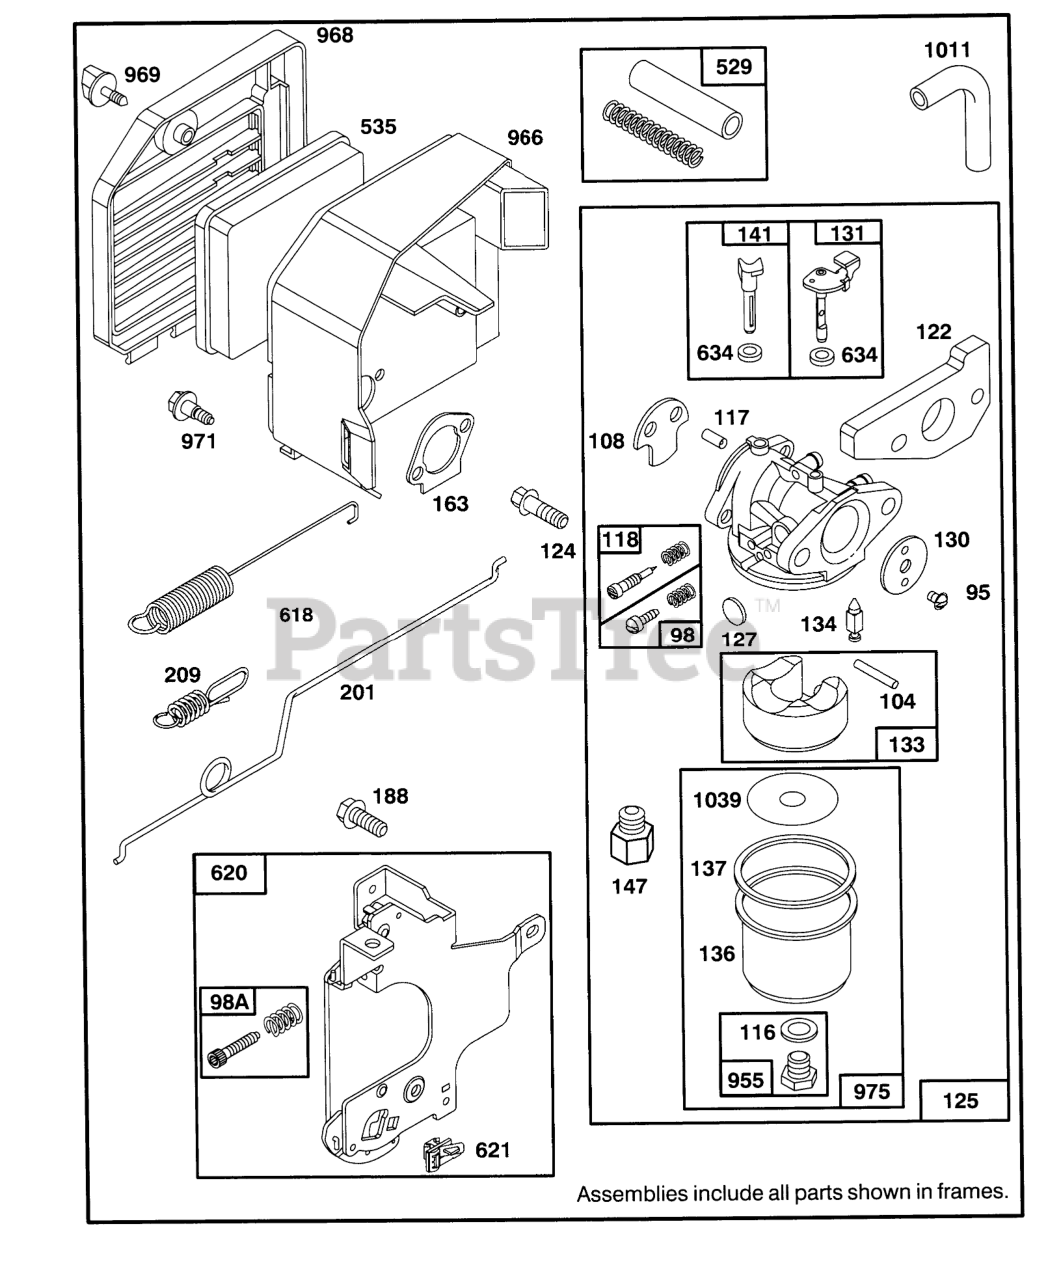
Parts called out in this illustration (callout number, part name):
95	SCREW - ROUND HEAD
98	IDLE ADJUSTING SCREW
98A	SPEED ADJUST. SCREW ASM
104	FLOAT HINGE PIN
108	CHOKE VALVE
116	SEALING GASKET
117	JET
118	VALVE KIT - NEEDLE
122	ADAPTER ASSEMBLY
124	HEX HEAD SCREW
125	CARBURETOR ASSEMBLY
130	THROTTLE VALVE
131	THROTTLE SHAFT
133	FLOAT-CARBURETOR
134	Valve-Float (Includes Seat)
136	FLOAT BOWL
137	FLOAT BOWL GASKET
141	CHOKE SHAFT
147	JET ADAPTER
163	AIR CLEANER GASKET
188	SCREW - SEM
201	GOVERNOR LINK
209	GOVERNOR SPRING
529	BREATHER TUBE
535	FILTER ELEMENT
618	RETURN SPRING
620	CARBURETOR BRACKET
621	STOP SWITCH
634	SEAL WASHER
955	HEX HEAD SCREW
966	AIR CLEANER BASE
968	AIR CLEANER COVER
969	AIR CLEANER SCREW
971	AIR CLEANER SCREW
975	CARBURETOR BOWL ASM
1011	VENT TUBE
1039	FLOAT LIMITER
